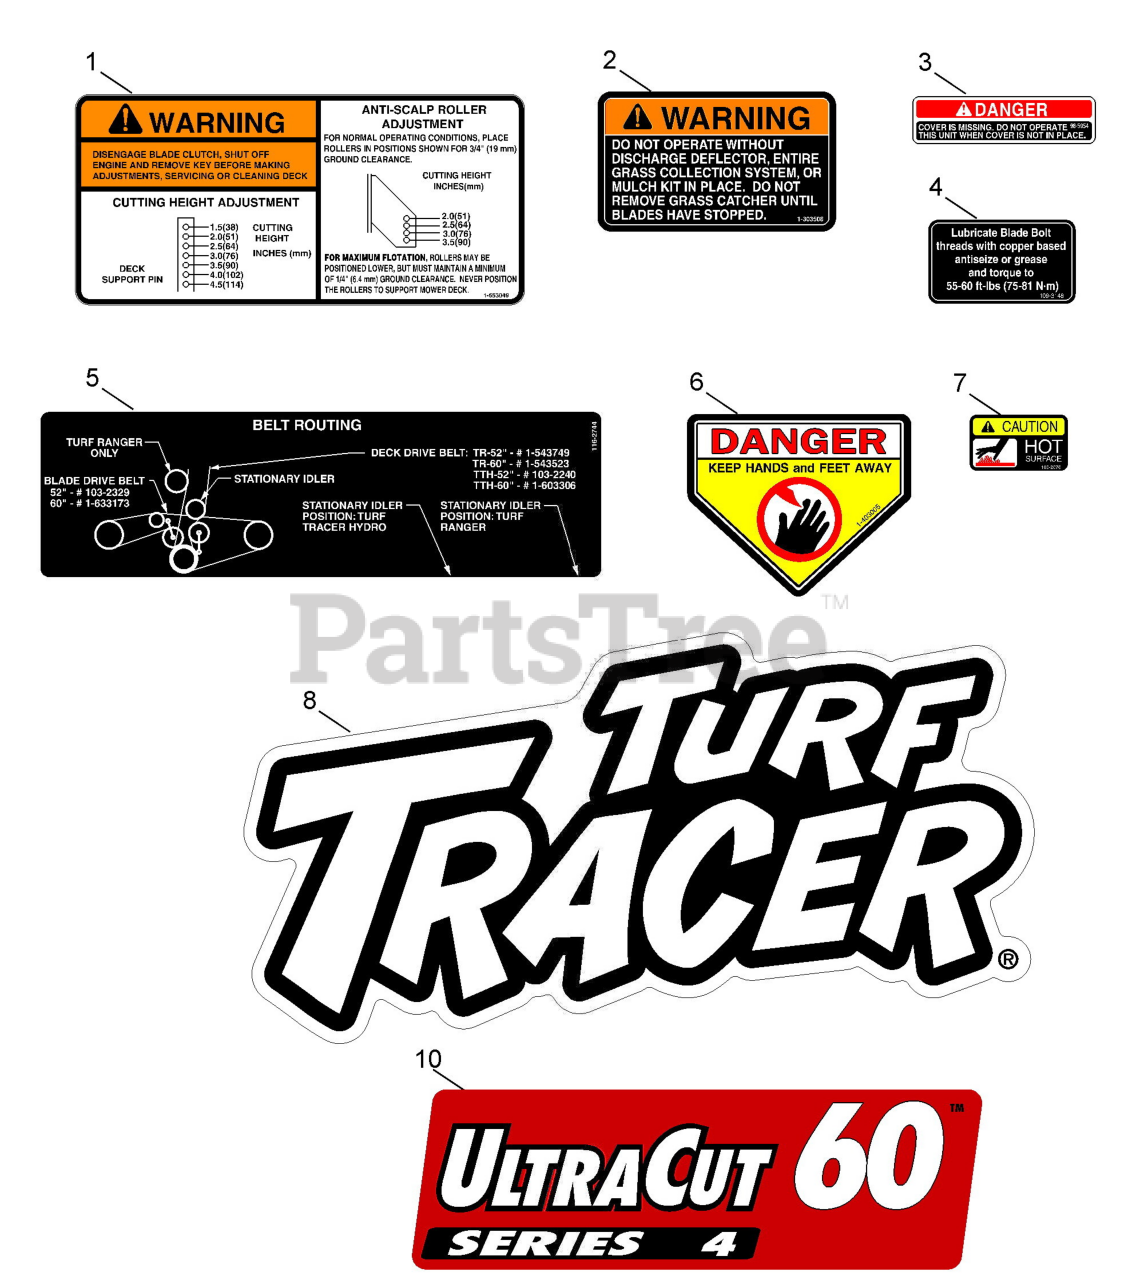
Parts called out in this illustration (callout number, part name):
1	DECAL,ANTI SCALP
2	DECAL-WARNING, DISCHARGE
3	DECAL-COVER, MISSING
4	DECAL,BOLT TORQUE
5	DECAL-BELT ROUTING
6	DECAL-DANGER
7	DECAL-CAUTION
8	DECAL,TTH MODEL
10	DECAL,ULTRACUT 60 SERIES
